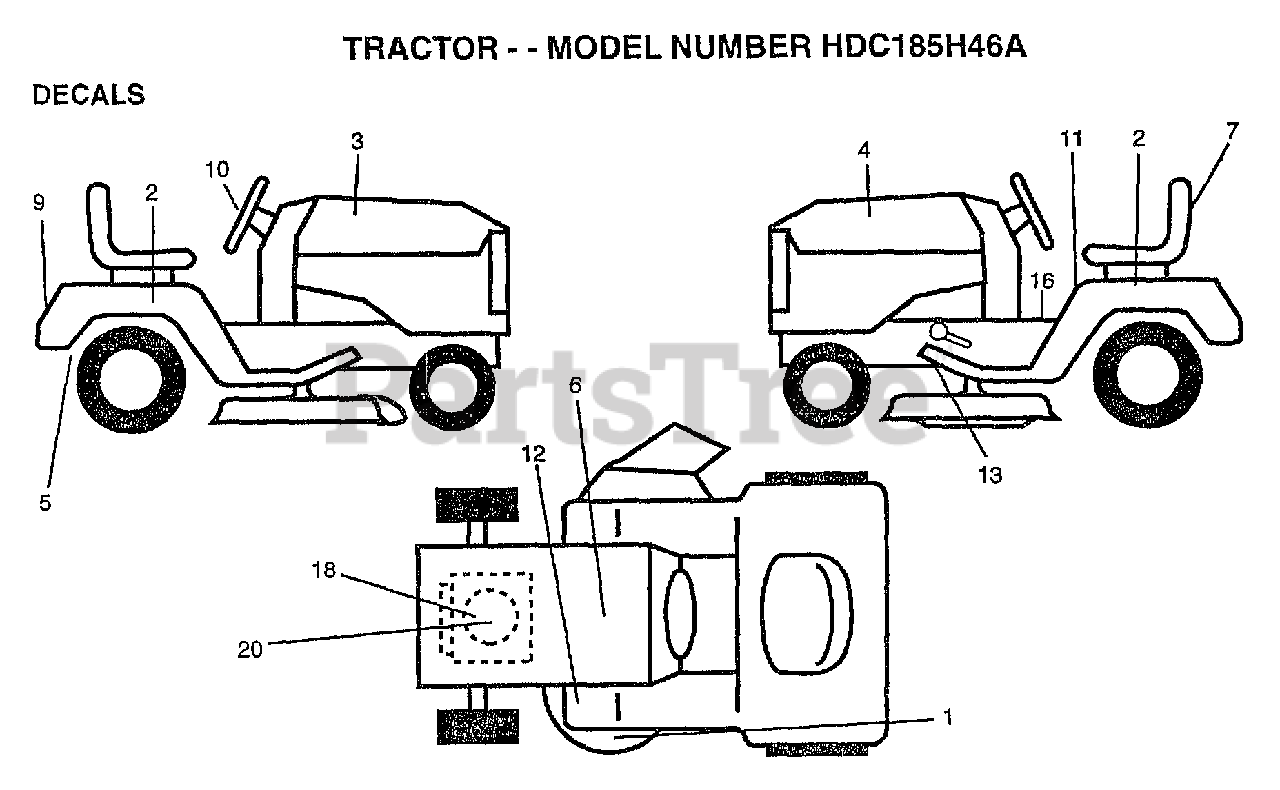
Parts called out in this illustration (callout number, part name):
1	"DECAL DECK,MULCH"
2	DECAL FENDER SIDE
3	"DECAL-HOOD,RH"
4	DECAL HOOD LH
5	DECAL DRAWBAR LH
6	DECAL.BATRY.3-3908
7	DECAL SEAT REPLCM
9	"DECAL FENDER,LOGO"
10	"DECAL WHEEL,STEER"
11	"DECAL FENDER,DANG"
12	DECAL CLUT/BRAKE
13	"DECAL.V.BELT.44"""
16	"DECAL-SADDLE,INST"
18	DECAL, HP ENGINE
20	DECAL ENG REPLCMT
